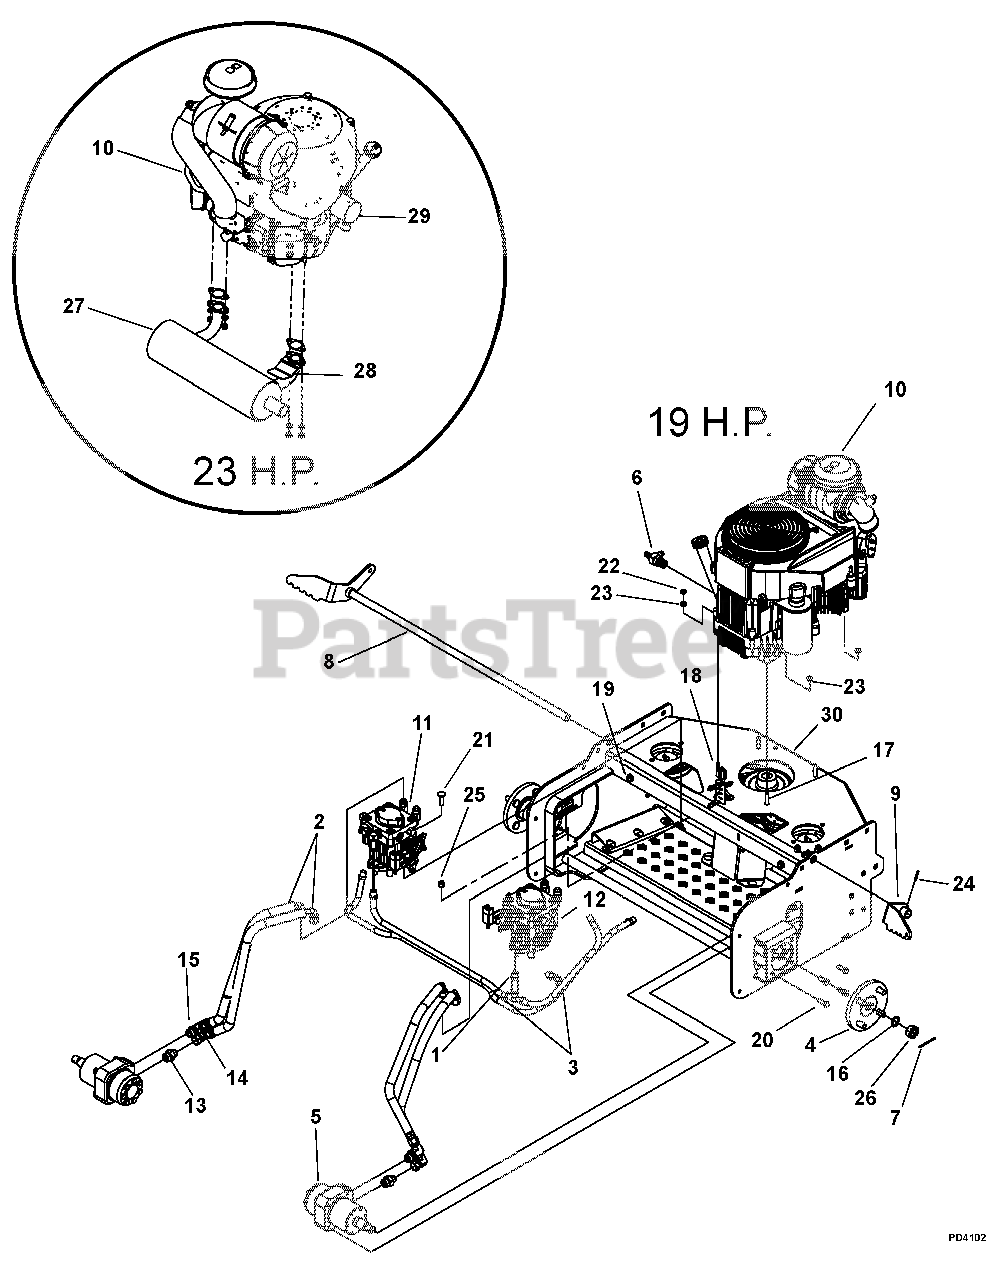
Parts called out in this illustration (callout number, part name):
1	Hose Clamp
2	Hose, High Pressure
3	Tee Fitting
4	Hub, Rear Wheel
5	Wheel Motor
6	Oil Drain Fitting
7	Pin, Center .125 x 2.00
8	Weldment, Brake Shaft
9	Weldment, RH Brake Arm
10	Engine, Kawasaki 19HP FH580V
11	Assembly, LH Hydraulic Pump
12	Assembly, RH Hydraulic Pump
13	Adapter, Hydraulic Steel 7/8 "0" to .75
14	Adapter, 3/4 FESW x 3/4 MJIC x 90
15	Adapter, 8MJ-10MB90
16	Shim, .020 x .787 x 1.102
17	Bolt, Hex .31-18 x 1.50 Grade 5
18	Bolt, Hex .31-18 x 1.75 Grade 5
19	Bolt, Hex .38-16 x 1.00 Grade 8 w/Epoxy Patch
20	Bolt, Hex .38-16 x 1.00 Grade 5
21	Bolt, Round Head Square Neck .38-16 x 1.25 Grade 5
22	Nut, Jam .312-18
23	Nut, Locking, Nylon .312-18
24	PIn, Roll .156 x 1.00
25	Nut, Locking, Nylon .38-16
26	Castle Nut
27	Muffler, Kawasaki Flat Head Horizontal (994102)
28	Shield, Heat
29	Oil Filter, Kawasaki # 49065-2078
30	Weldment, Deck Frame w/Decals S/O
